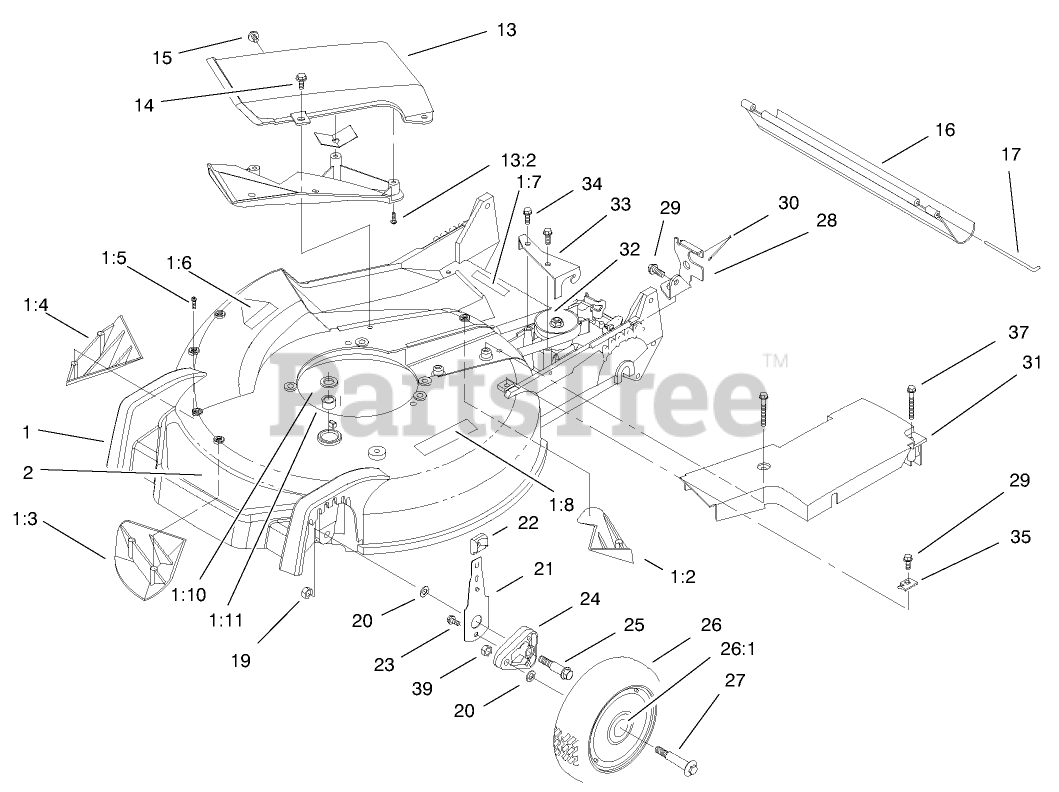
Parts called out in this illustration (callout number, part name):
1	HOUSING
1:2	KICKER-REAR
1:3	KICKER-FRONT
1:4	KICKER-RH
1:5	SCREW-PPH
1:6	DECAL-DANGER
1:7	DECAL-WARNING
1:10	WASHER
1:11	BEARING
2	DECAL-DECK
13	RECYCLER COVER ASM
13:2	SCREW-PPH
14	SCREW-HWH
15	SCREW AND WASHER ASM
17	ROD-SHIELD
19	NUT-LOCK
20	WASHER
21	FRONT SPRING ARM ASM
22	KNOB-ARM
23	SCREW-HWH
24	ARM-PIVOT, FRONT
25	BOLT-SHOULDER
26	WHEEL ASM
26:1	BUSHING
27	BOLT-SHOULDER
28	BRACKET-TRACTION, ADJ.
29	SCREW-HWHTF
30	RETAINER-CABLE
32	GEARCASE ASM
33	BRACKET-GUIDE, BELT
34	SCREW-HWHTF
35	CLAMP-CABLE
37	SCREW-HWH
39	LOCKNUT
